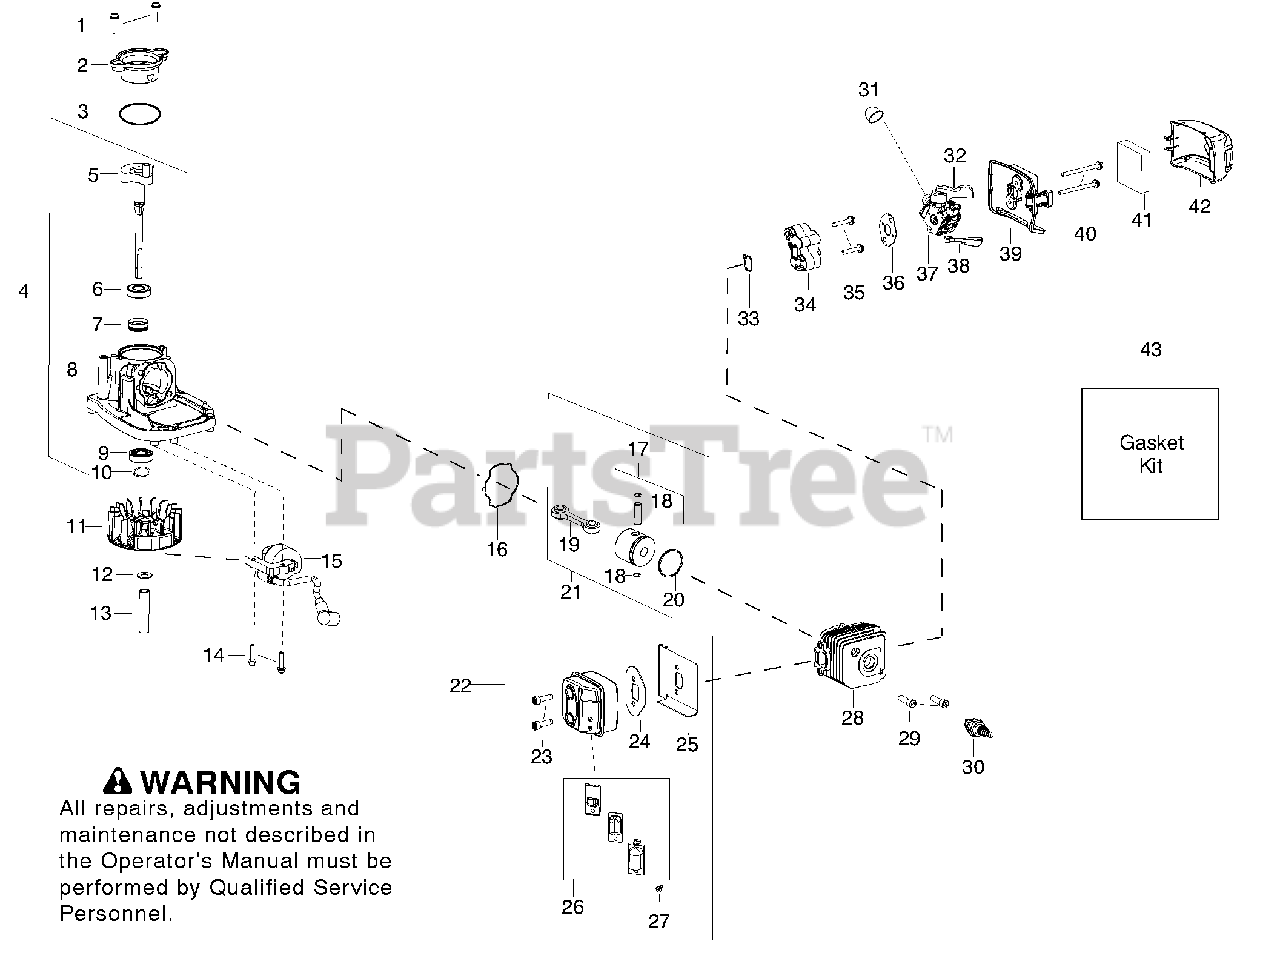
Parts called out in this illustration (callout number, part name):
2	Assy - Rear Plug
3	O-Ring - Rear Plug (kit)
4	Kit - Crankshaft / Crankcase
5	Assy - Crankshaft
6	Bearing - Inner
7	Seal - Crankshaft
8	Assy - Crankcase
9	Bearing - Outer
10	Ring - Crankshaft Retainer
11	Assy - Flywheel
13	Spacer - Flywheel
15	Module - Ignition
16	Seal - Crankcase / Cylinder (kit)
17	Kit - Piston
18	Retainer - Wrist Pin
19	Kit - Connecting Rod
20	Ring - Piston
21	Kit - Piston and Rod
22	Kit - Muffler
23	Screw - Muffler
24	Gasket - Muffler (kit)
25	Shield - Muffler
26	Kit - Spark Arrestor
27	Screw
28	Cylinder - Machined (25cc)
29	Screw - Cylinder
30	Accy - Spark Plug (RCJ-6Y)
32	Kit - Throttle
33	Seal - Cylinder/Carb. Adapter (kit)
34	Adapter - Carburetor
36	Gasket - Carburetor (kit)
37	Kit - Carburetor Assy.
39	Base - Air Box
41	Filter - Foam Air
42	Cover - Air Box
43	Kit - Gasket
